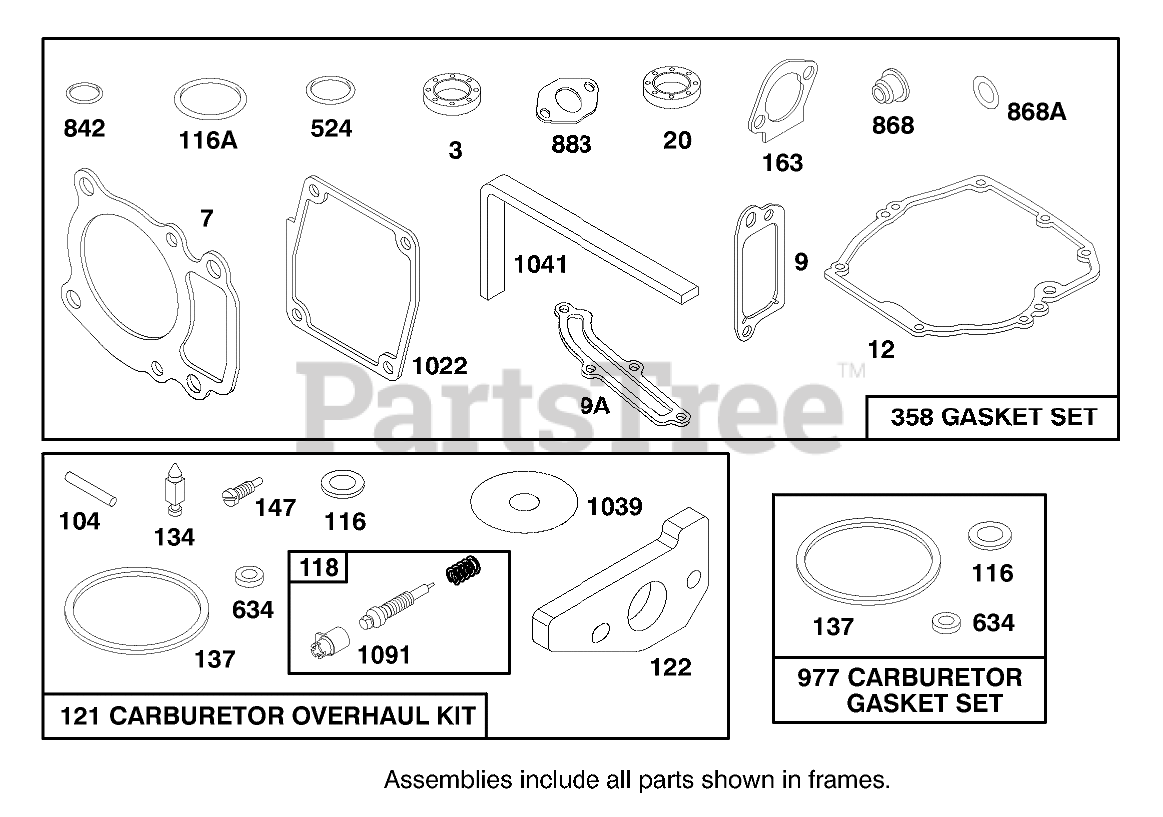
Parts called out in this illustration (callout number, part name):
3	SEAL - OIL
7	CYLINDER HEAD GASKET
9	BREATHER GASKET
9A	GASKET-BREATHER
12	ENGINE BASE GASKET
20	SEAL-OIL
104	FLOAT HINGE PIN
116	O RING SEAL
116A	SEALING GASKET
118	VALVE/SPRING - NEEDLE
121	KIT-CARBURETOR OVERHAUL
122	ADAPTER ASSEMBLY
134	Valve-Inlet (Includes Seat)
137	FLOAT BOWL GASKET
147	JET - PILOT
163	AIR CLEANER GASKET
358	GASKET SET
524	O-RING
634	SEAL WASHER
842	O-RING
868	SealAssy-Valve
868A	Seal-Valve
883	EXHAUST GASKET
977	CARBURATOR GASKET SET
1022	ROCKER COVER GASKET
1039	FLOAT LIMITER
1041	SEAL - FOAM
1091	CAP - LIMITER
